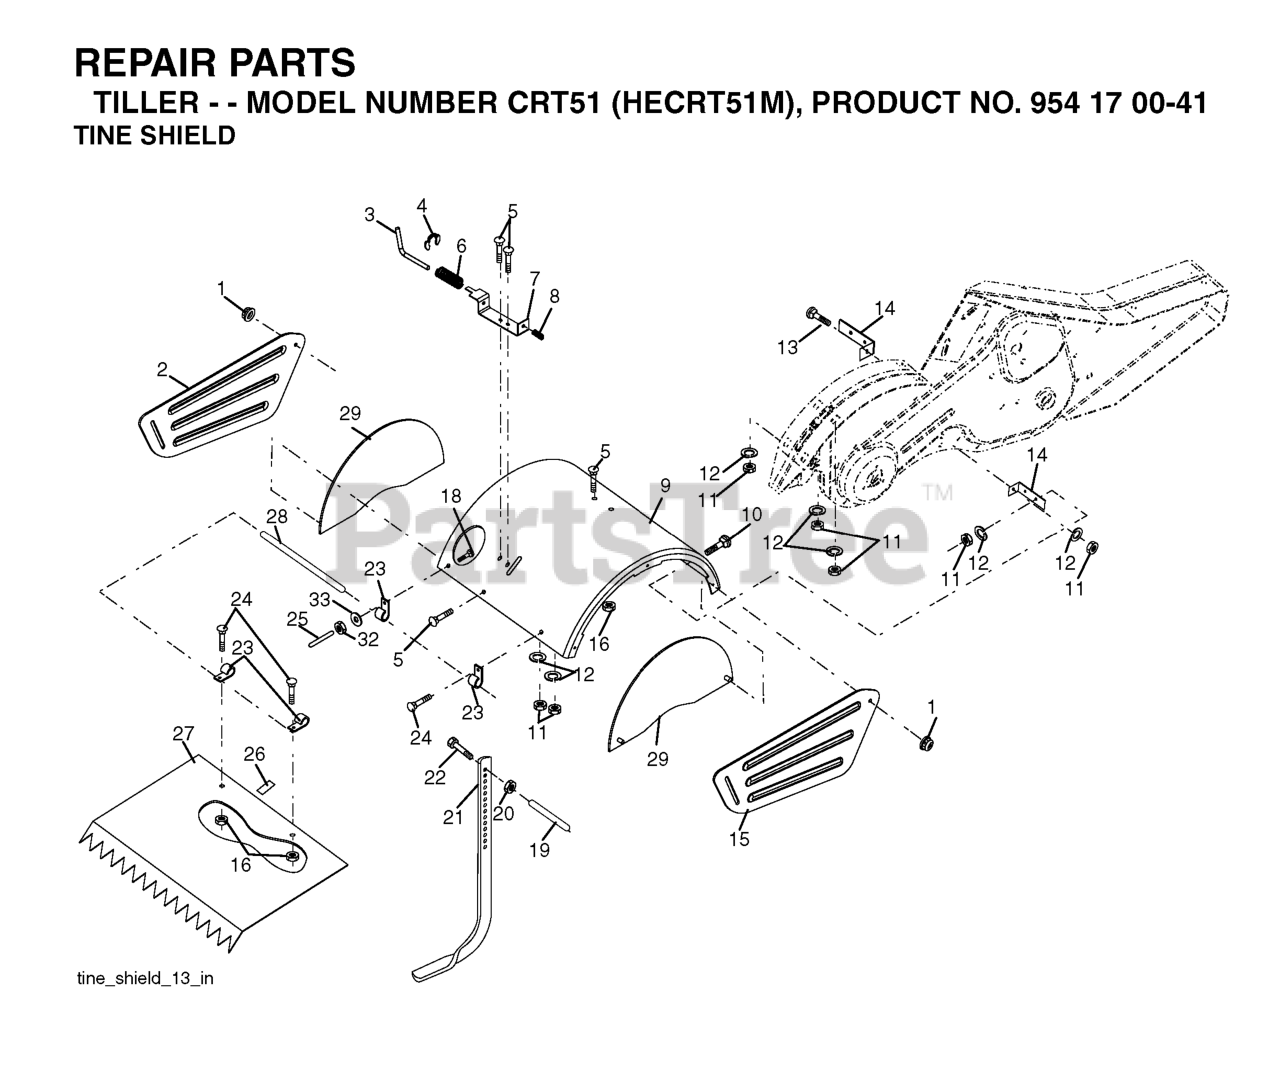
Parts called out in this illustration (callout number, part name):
1	NUT LOCK HEX FLANGE 5/16-18
2	SHIELD
3	STAKE PIN TI
4	RING, KLIP
5	BOLT, RDHD SQNK 5/16-18 X 3/4
7	BRACKET.LATCH.STAKE.3.20.BLACK
8	SPRING CRT
9	SHIELD
12	WASHER.LOCK.HVY.HLCL.SPR.5/16
13	BOLT.CARRIAGE.5/16-18
14	BRACKET.TINE.SHIELD.TILLER.BLA
15	SIDE SHIELD RH
16	NUT T
20	NUT.HEX.3/8-16UNC
21	STAKE.DEPTH.16.CRT.BLACK
22	BOLT.375-16
25	VINYL CAP TI
26	PAD IDLER TI
27	SHIELD LEVELING
28	PIN.HINGE.TILLER
29	SIDE SHIELD
30	LOCKNUT-FLANGE 5/16-18
32	NUT
33	LOCKWASHER
